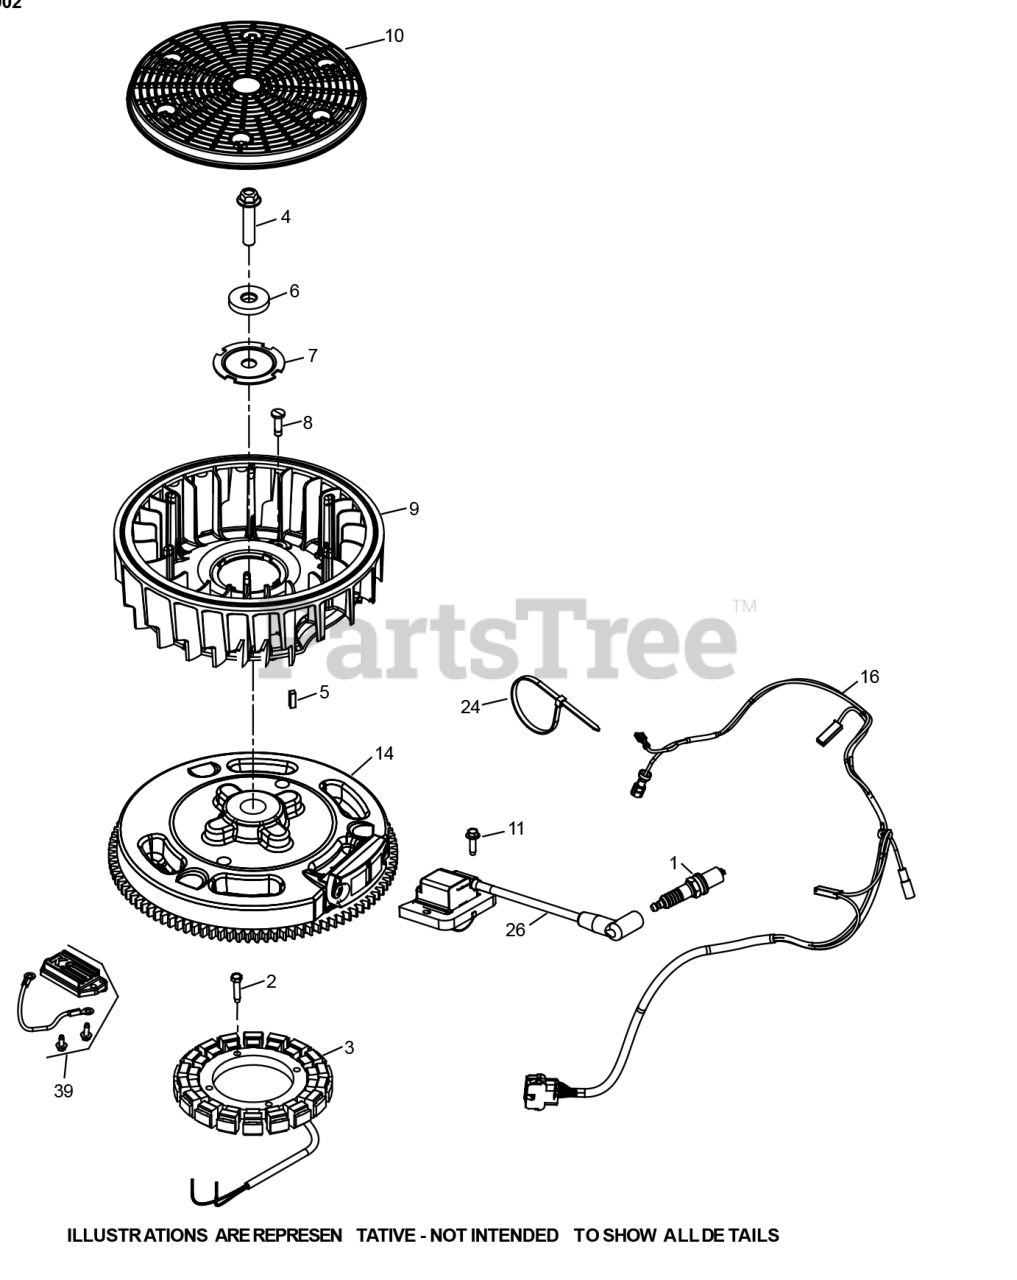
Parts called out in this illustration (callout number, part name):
1	SPARK PLUG RFI
2	THREAD FORMING SCREW
3	KIT-STATOR
4	HEX FLANGE BOLT
7	PLATE-FAN MOUNTING
11	THREAD FORMING SCREW
14	FLYWHEEL ASSEMBLY
16	WIRING HARNESS
26	IGNITION MODULE
39	REGULATOR RECTIFIER KIT
